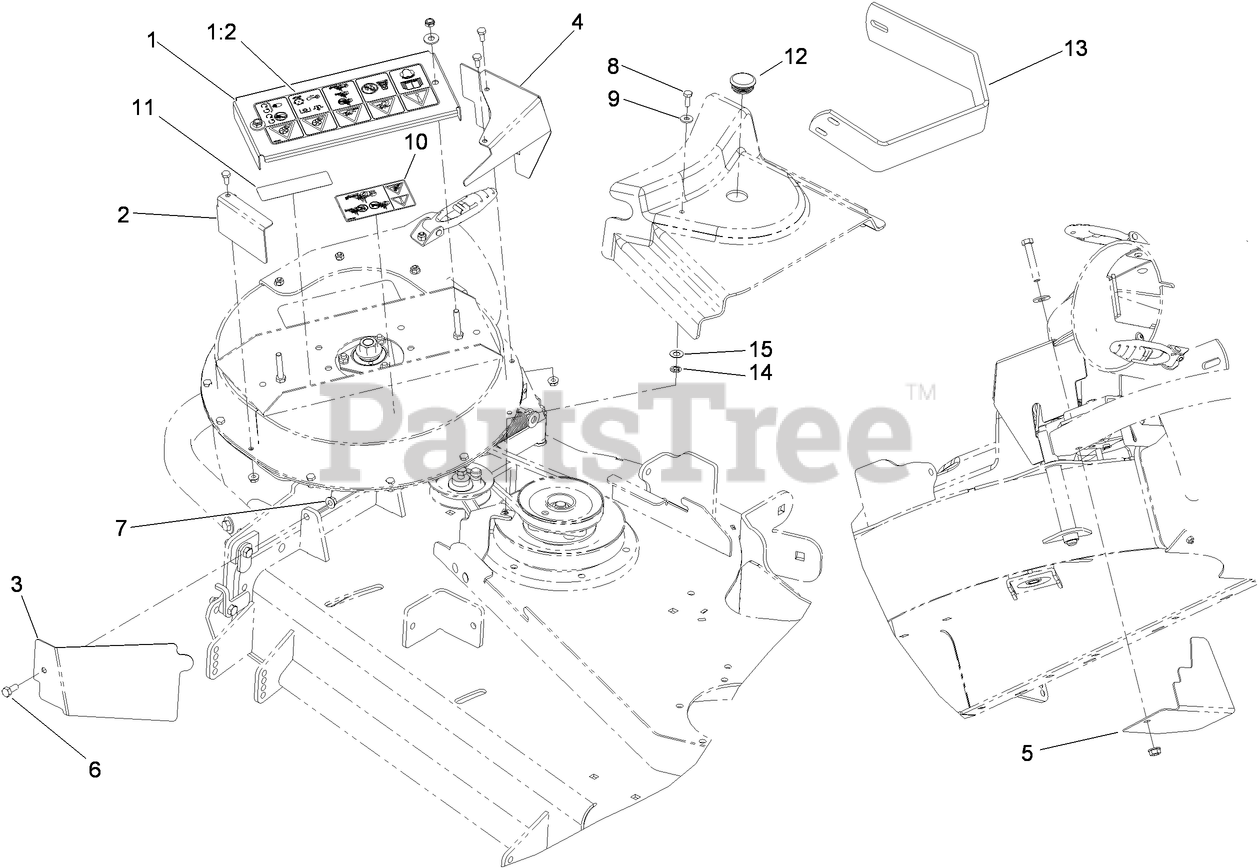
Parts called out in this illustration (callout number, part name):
1	BEARING COVER ASM
1:2	DECAL-DANGER
2	GUARD-LEFT
3	GUARD-FRONT
4	GUARD-BACK
5	GUARD-LOWER
6	SCREW-HH
7	NUT-HF
8	SCREW-HH
9	WASHER-FLAT
10	DECAL-WARNING
11	DECAL-MISSING, COVER
12	PLUG-PLASTIC
13	GUARD-MUFFLER
14	NUT-RETAINER
15	WASHER-FLAT
